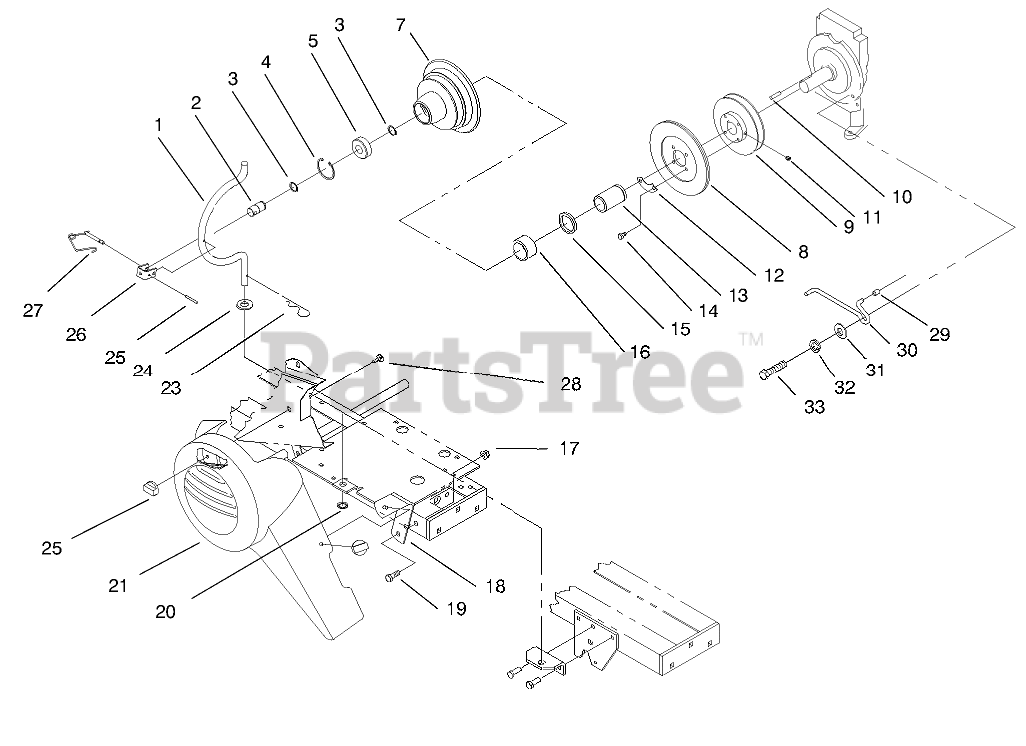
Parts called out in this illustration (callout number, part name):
1	ROD-HOUSING
2	SHAFT-PTO
3	Ring-Snap
4	RING-RETAINING
5	BEARING-BALL
7	Housing-Clutch
8	ASS'Y-CLUTCH PLATE
9	PULLEY
11	SCREW-SET, HSH
12	RETAINER
13	RACE-BEARING
14	SCREW-HEX HD CAP
15	SEAL-OIL
16	Seal
17	NUT-FLANGE
18	Bracket
19	SCREW-HH
20	RING-REINFORCED CIRC
21	GUARD - BELT
22	NUT - WING
23	PIN-COTTER, HAIR
24	WASHER-FLAT
26	CLEVIS
27	LOCKING PIN ASM
28	Retainer-Bolt
30	GUIDE BELT
31	WASHER-FLAT
32	WASHER-LOCK
33	SCREW-HH
